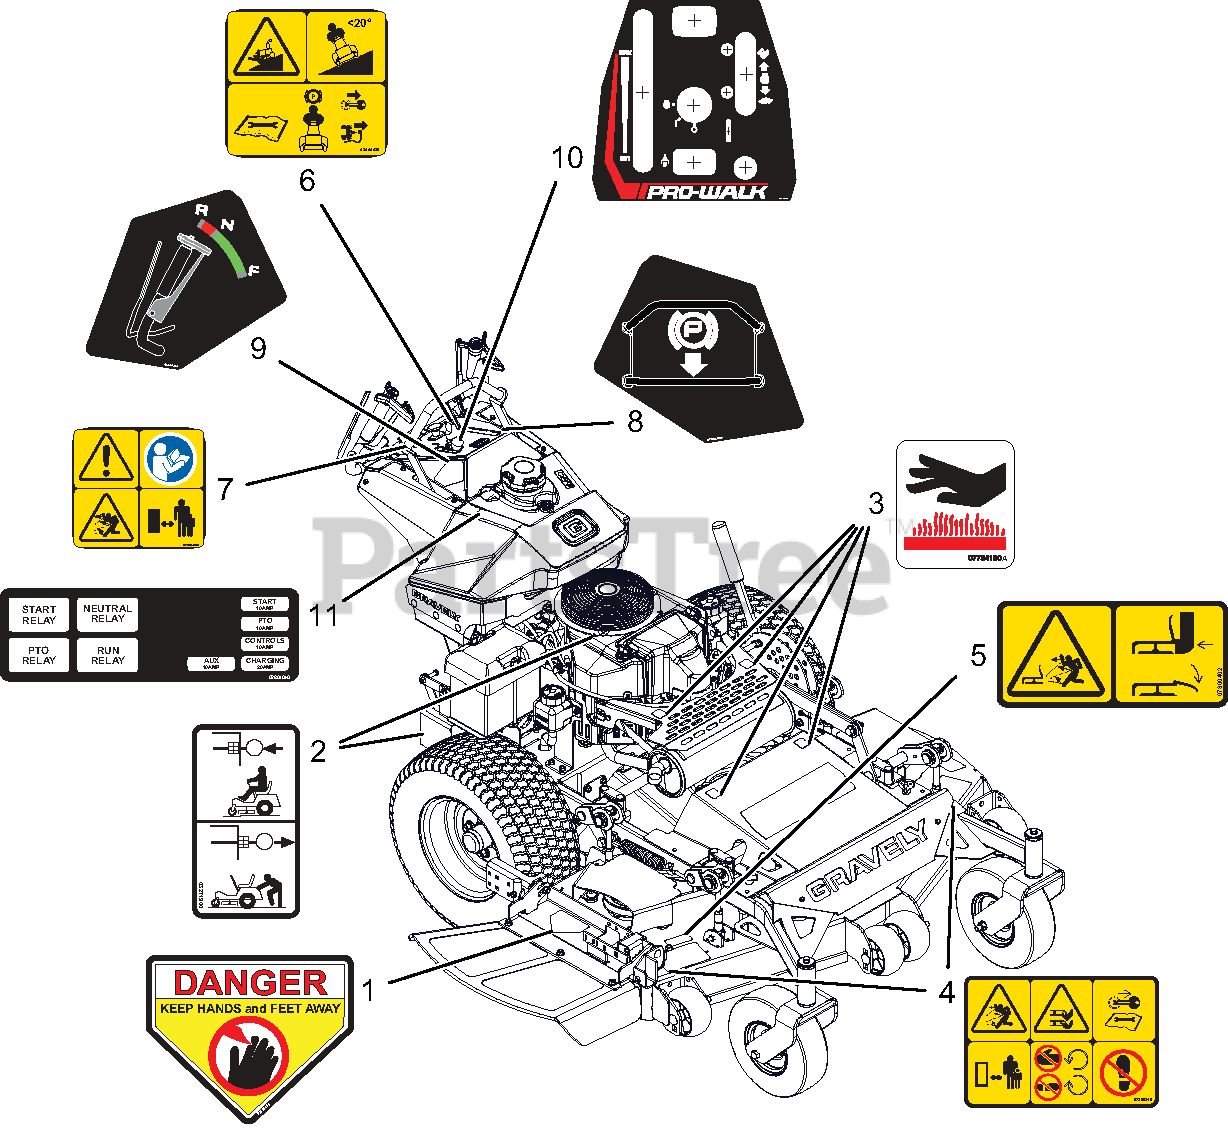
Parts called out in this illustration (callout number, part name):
1	DECAL, DANGER
2	DECAL, TRANSMISSION DISCONNECT
3	DECAL, HOT SURFACE
4	DECAL, SAFETY - MOWER DECK
5	DECAL, SAFETY - DECK GUARDING
6	DECAL, SAFETY - DECK GUARDING
7	DECAL, SAFETY
8	DECAL, SAFETY
9	DECAL, DIRECTION CONTROL
10	DECAL, CONTROL PANEL
11	DECAL, FUSE BOX - PROWALK
